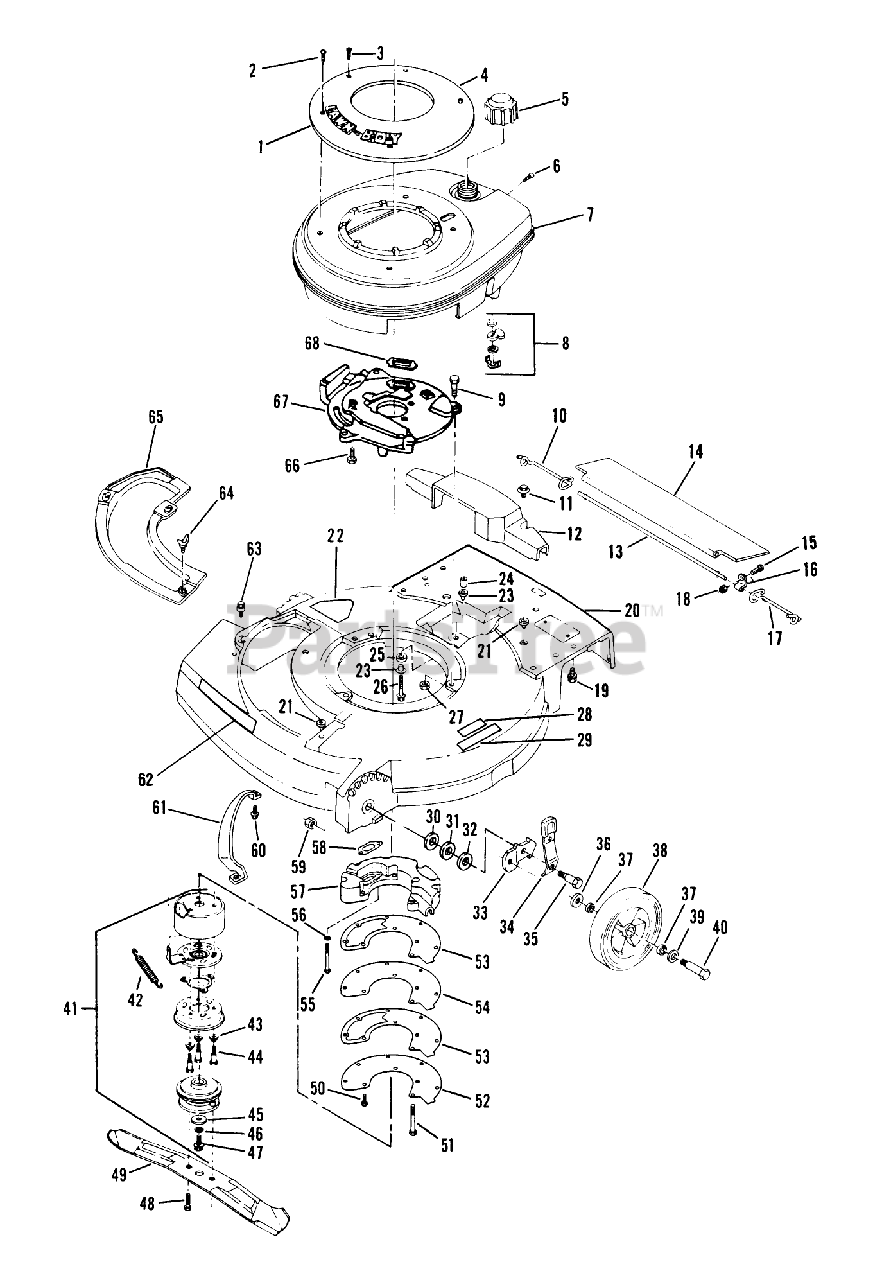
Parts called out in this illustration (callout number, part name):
2	SCREW - SELF TAPPING
3	SCREW SEMS SM
5	FUEL CAP & INSERT
6	SCREW S
8	SHUT OFF VALVE KIT
9	SCREW-HH
10	SPRING;TRAILING SHIELD RH
11	SCREW SEMS TRM HEX HD
13	ROD 21" ADVANCE
14	SHIELD
16	CLAMP ROD KMC
17	SPRIG T/SHLD ASOC
18	LOCKNUT E
19	SCREW
23	SPACER ECK PRES
24	SPACER
25	GROMMET
27	NUT-LOCK F
29	PAD FOOT
30	WASHER
31	WASHER
32	WASHER
34	SPRING ARM ASM
35	BOLT
36	WASHER WROUGHT
37	WASHER
38	WHEEL & TIRE KIT
39	SPACER
40	BOLT WHEEL
42	SPRING
44	SCREW,SHOULDER SM
45	WASHER
48	SCREW SEMS
49	21" Blade
50	SCREW
53	GASKET F
59	LOCKNUT
61	BAR-TOE
64	Wing Screw
